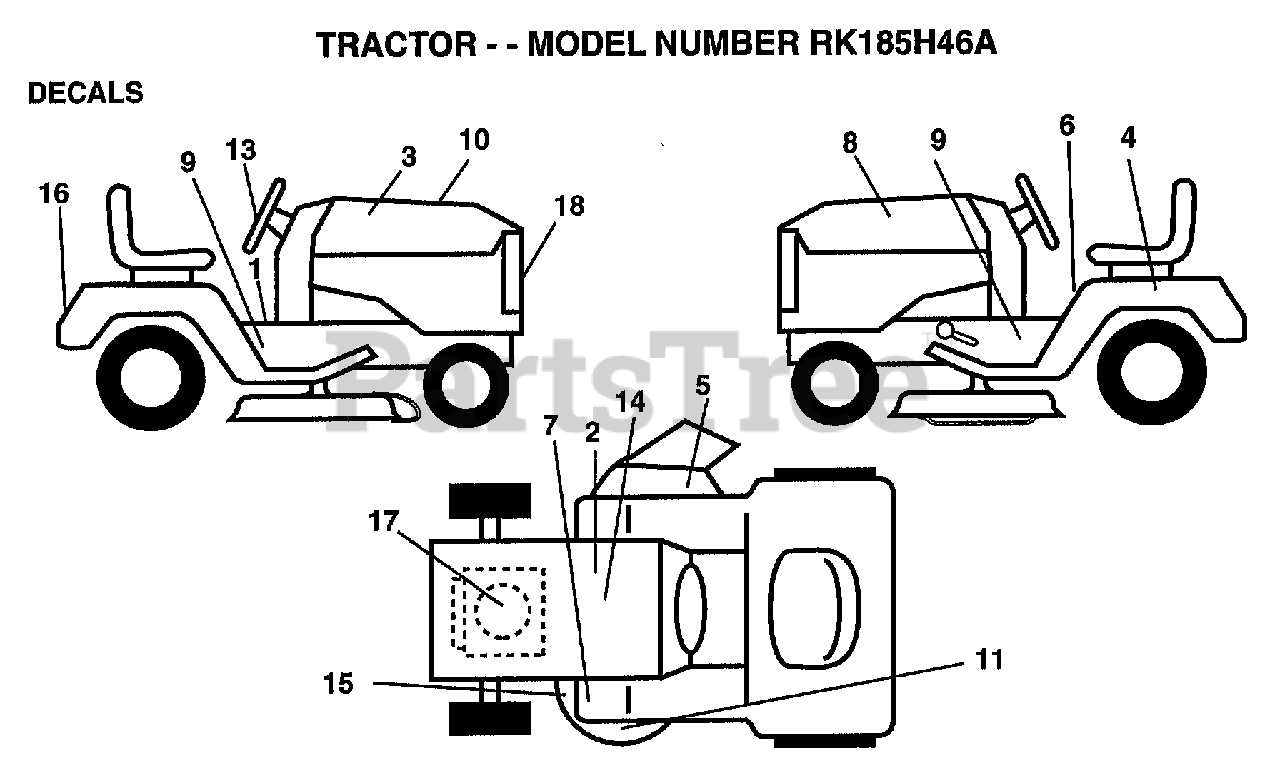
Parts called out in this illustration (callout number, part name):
1	DECAL SADDLE OPER
3	DECAL.FENDER.RH
4	DECAL.FENDER.SIDE
5	"DECAL, WARNING"
6	DECAL.CAUT.ENG/FR
7	DECAL T
8	DECAL.HOOD.RH
11	DECAL.MOWER
13	DECAL
14	DECAL.BATRY.3-3908
15	"DECAL.V.BELT.44"""
16	DECAL.FENDER.LOGO
17	DECAL.HP.ENGINE
18	GRILLE.LENS.EURO
